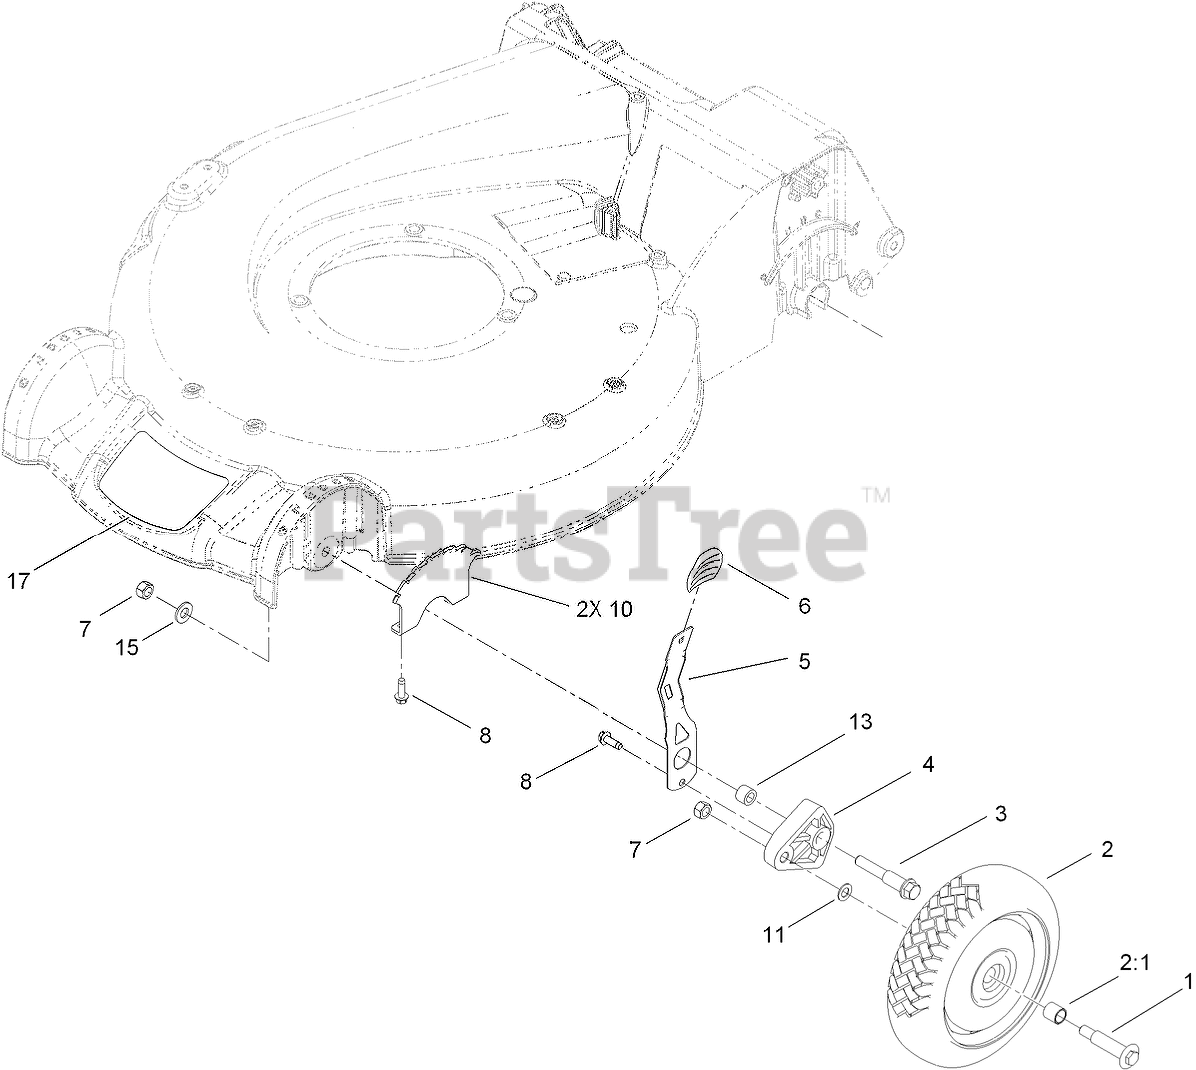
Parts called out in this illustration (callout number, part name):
1	BOLT-SHOULDER
2	WHEEL ASM
2:1	BUSHING
3	SCREW-SHOULDER
4	ARM-PIVOT
5	ARM-SPRING
6	Knob-Lever, HOC
8	SCREW-HWHTF
10	PLATE-HOC
11	WASHER
13	SPACER-WHEEL
15	WASHER-FLAT
17	DECAL-HOUSING
